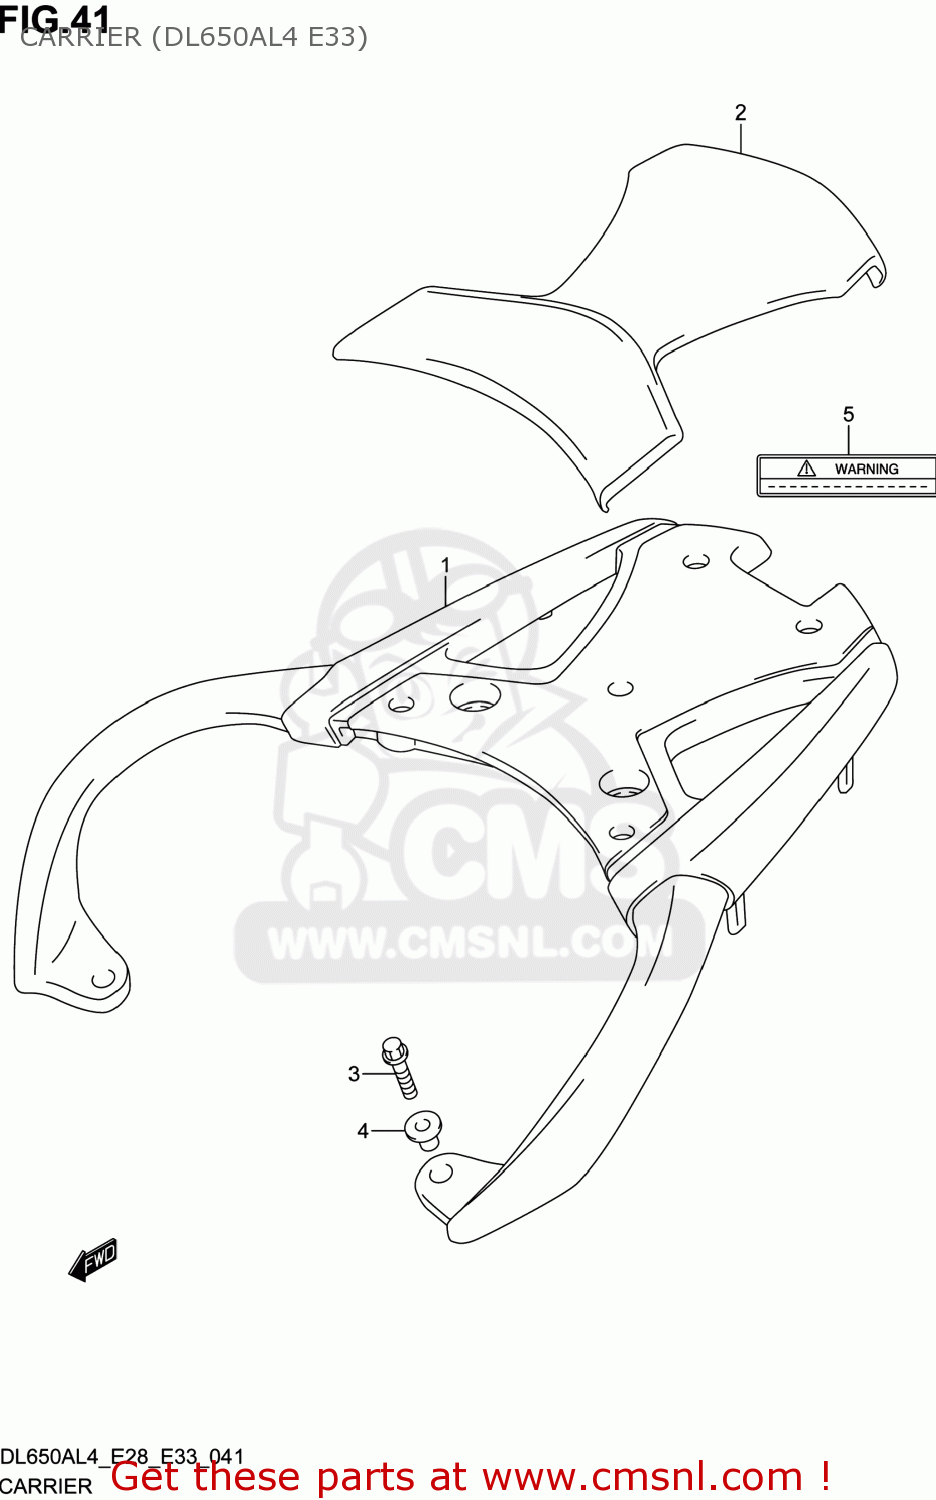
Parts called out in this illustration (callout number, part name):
1	CARRIER,SPORT
2	MAT,SPORT CARRIER
3	BOLT(8X35)
4	WASHER
5	LABEL,WARNING LUGGAGE CARRIER
